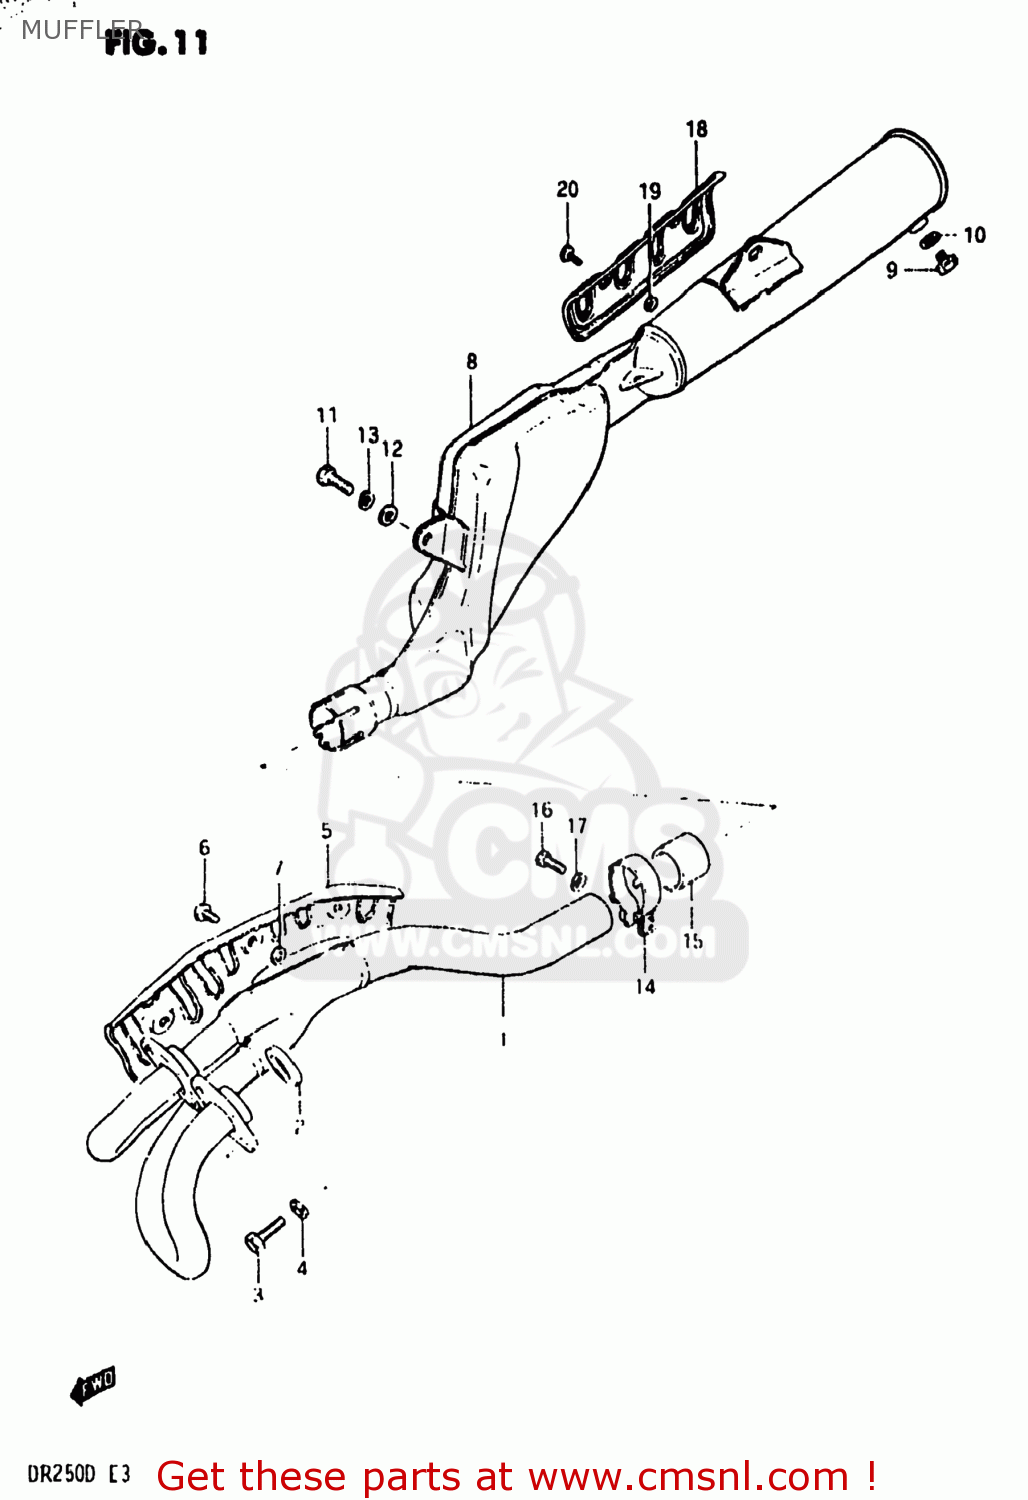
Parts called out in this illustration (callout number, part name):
1	PIPE,EXHAUST
2	GASKET,EXHAUST PIPE (NAS)
3	BOLT
4	LOCK WASHER
5	COVER,EXHAUST PIPE
6	SCREW
7	GASKET 6.2X12X1.5 (MCA)
8	MUFFLER ASSEMBLY
9	PLUG(12X9)
10	GASKET(12.1X16.2X3.7) (NAS)
11	BOLT
12	WASHER,8.5X16X
13	LOCK WASHER
14	CLAMP
15	CONNECTOR,MUFFLER
16	BOLT 8X35
17	WASHER,8.5X16X
18	COVER,MUFFLER
19	GASKET 6.2X12X1.5 (MCA)
20	SCREW
